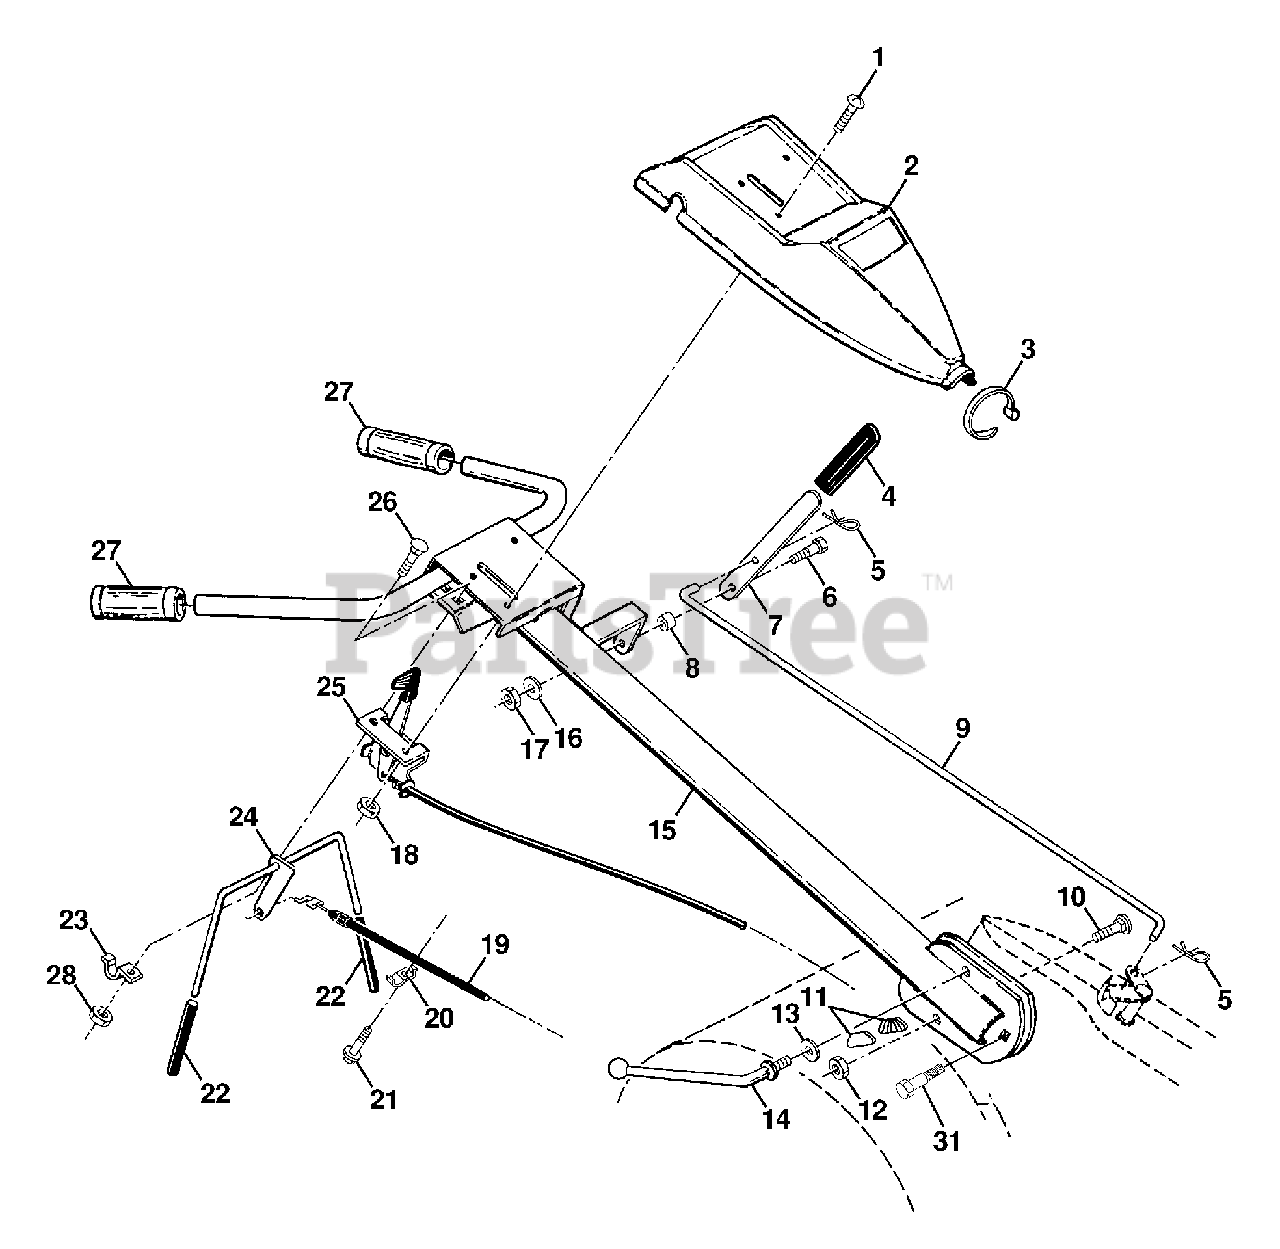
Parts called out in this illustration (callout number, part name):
1	Screw, Phd. #10-24 UNC
2	Panel, Control
3	Tie, Cable
4	Grip, Handle
5	Clip, Hairpin
6	Bolt, Shoulder
7	Handle, Shift
8	Grommet, Rubber
9	Rod, Shift
10	Bolt, Carriage 3/8-16 x 1 Gr. 5
11	Lock, Handle
12	Nut, Centerlock 3/8-16
13	Washer 13/32 x 1 x 11 Ga.
14	Lever, Lock, Handle
15	Handle
16	Washer, Lock 1/4
17	Nut, Hex 1/4-20
18	Nut, Keps #10-24 UNC
19	Cable, Clutch
21	Screw, Hex Washer Hd. Slotted #10-24 x 1/2
22	Grip, Bar, Control
23	Clamp, Bar, Control
24	Bar Assembly, Control
25	Control, Throttle
26	Bolt, Carriage 1/4-20 UNC x 1/2
27	Grip, Handle
28	Nut, keps 1/4-20
31	Bolt Pivot
